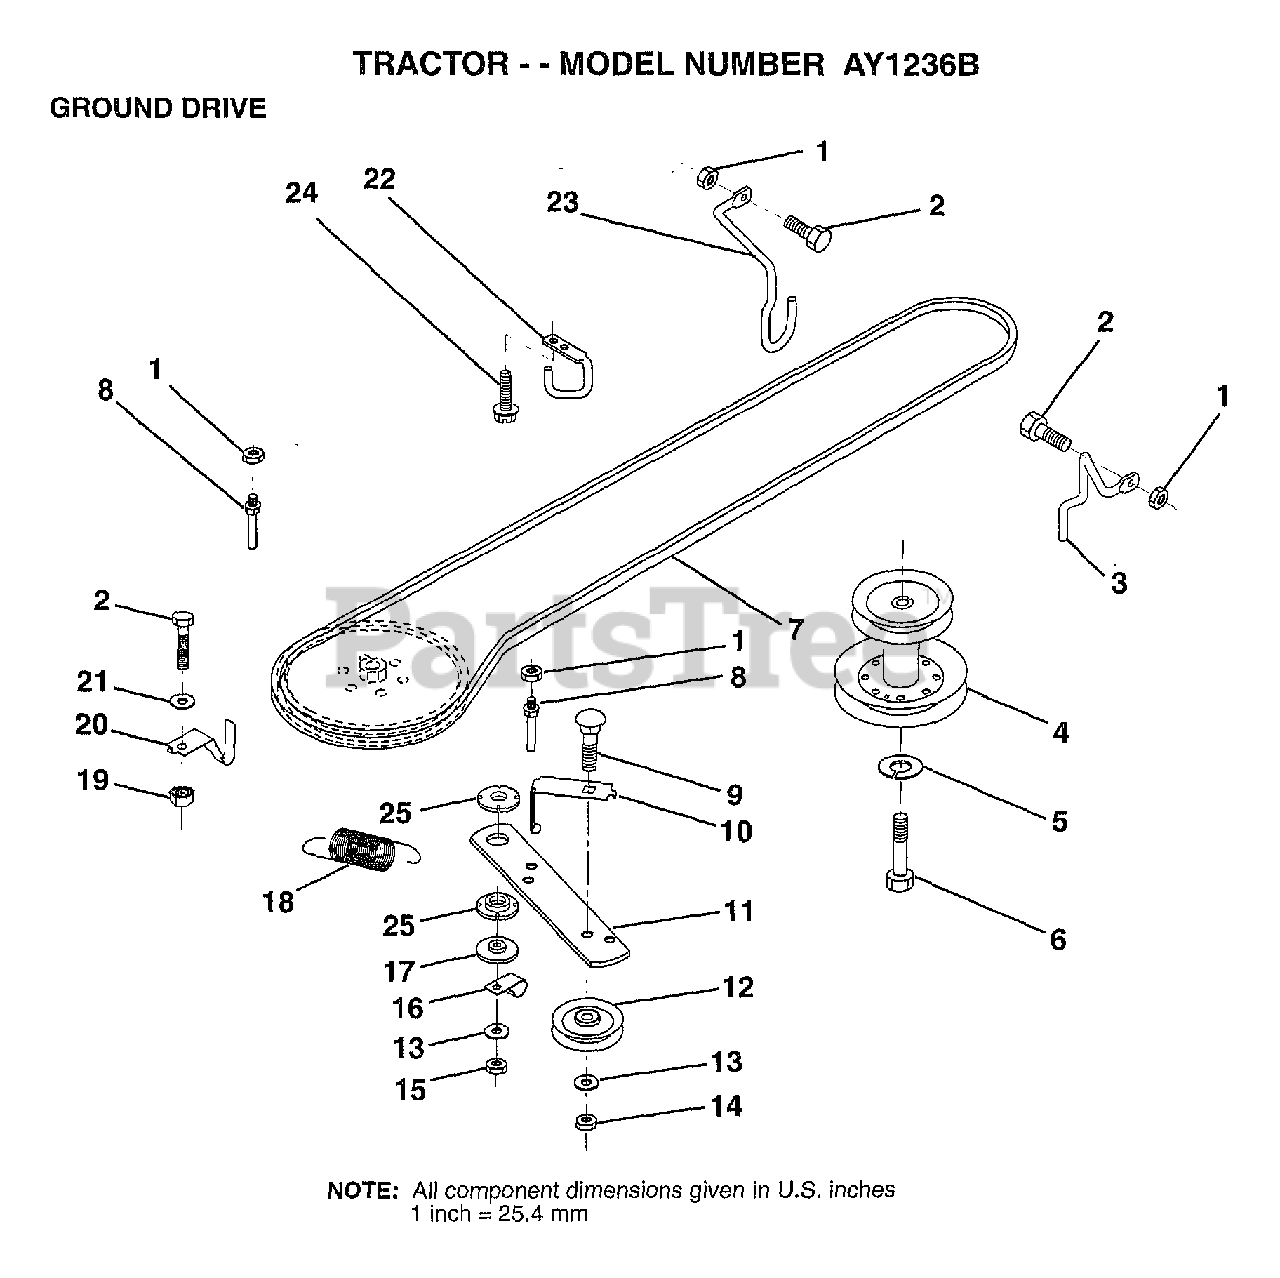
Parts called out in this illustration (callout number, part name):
2	BOLT
3	KEEPER RH
4	PULLEY.ENGINE.LR
5	LOCKWASHER
6	HEX BOLT
7	BELT
8	"KEEPER,DRIVE BELT"
9	BOLT
10	"KEEP,IDLER DR BEL"
11	ARM-IDLER.DR.GRND
12	PULLEY.IDLER.FLAT
13	WASHER
14	LOCKNUT
16	"CLIP,INSULATOR"
17	SPACER
20	KEEPER.BELT.T/A
21	WASHER
22	"KEEPER,FRA DR BEL"
23	KEEPER MOWER LH
24	SCREW
25	BUSHING.NYLON
